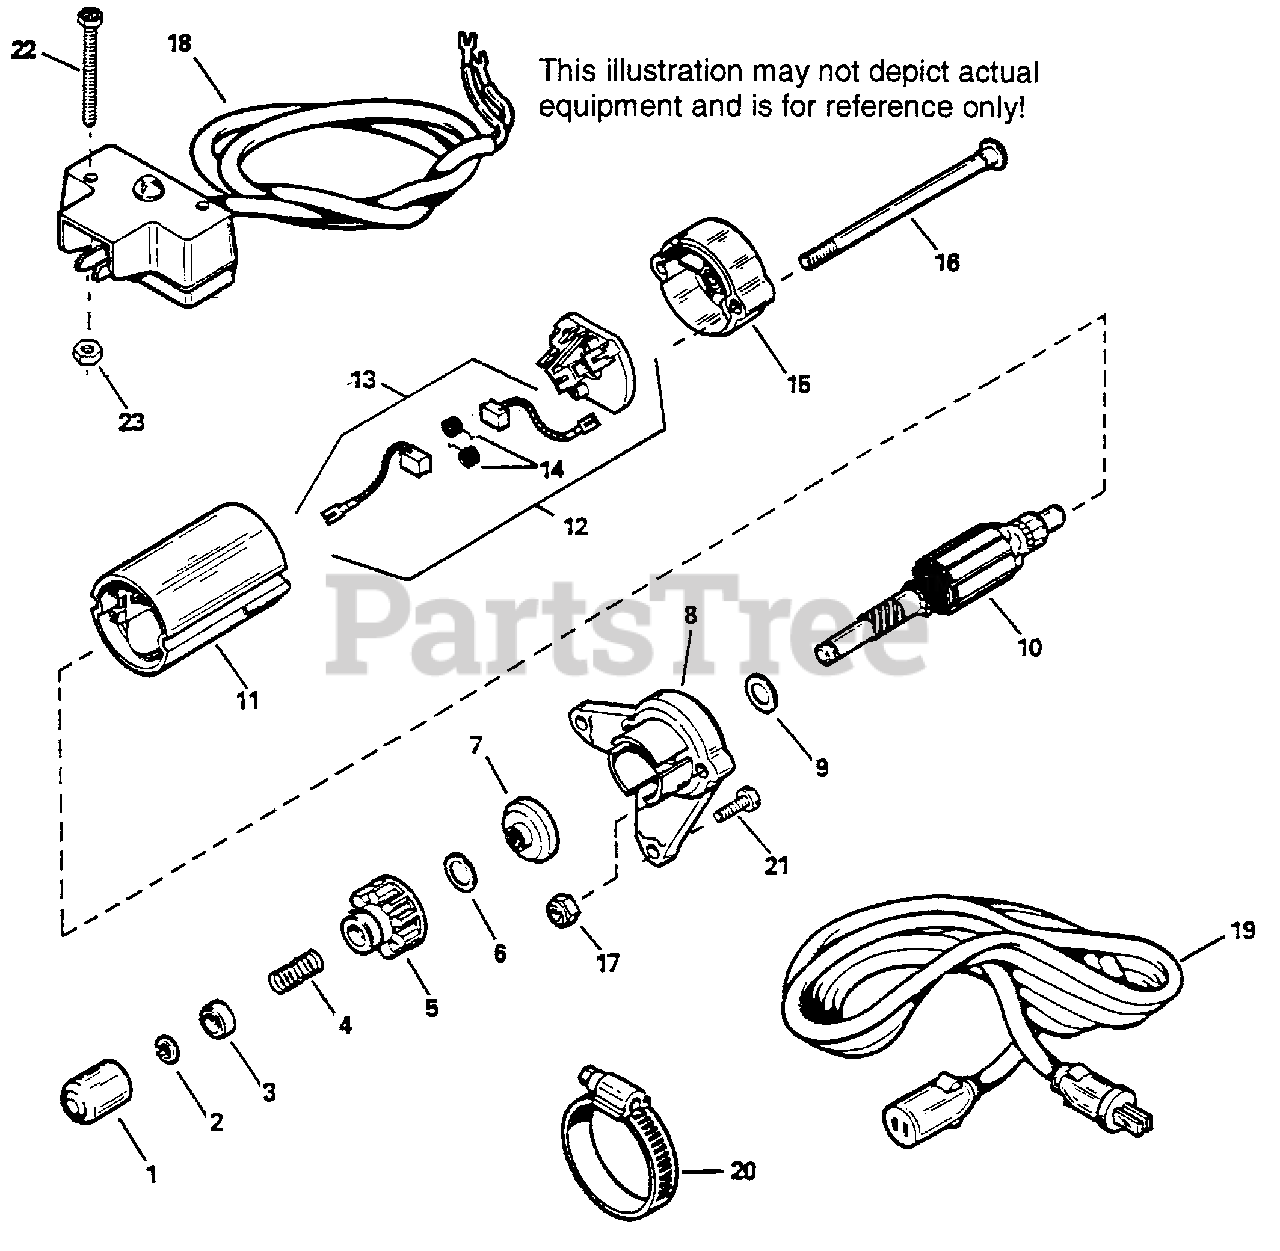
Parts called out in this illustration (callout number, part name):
1	Dust Cover
2	Retaining Ring
3	Spring Retainer
4	Anti-drift Spring
7	Engaging Nut
19	Extension Cord (10'6")
20	Hose Clamp (Can be purchased locally)
21	Screw, 1/4-20 x 7/8"
22	Screw, 6-32 x 2-1/2"
23	Nut & Washer Ass'y.
